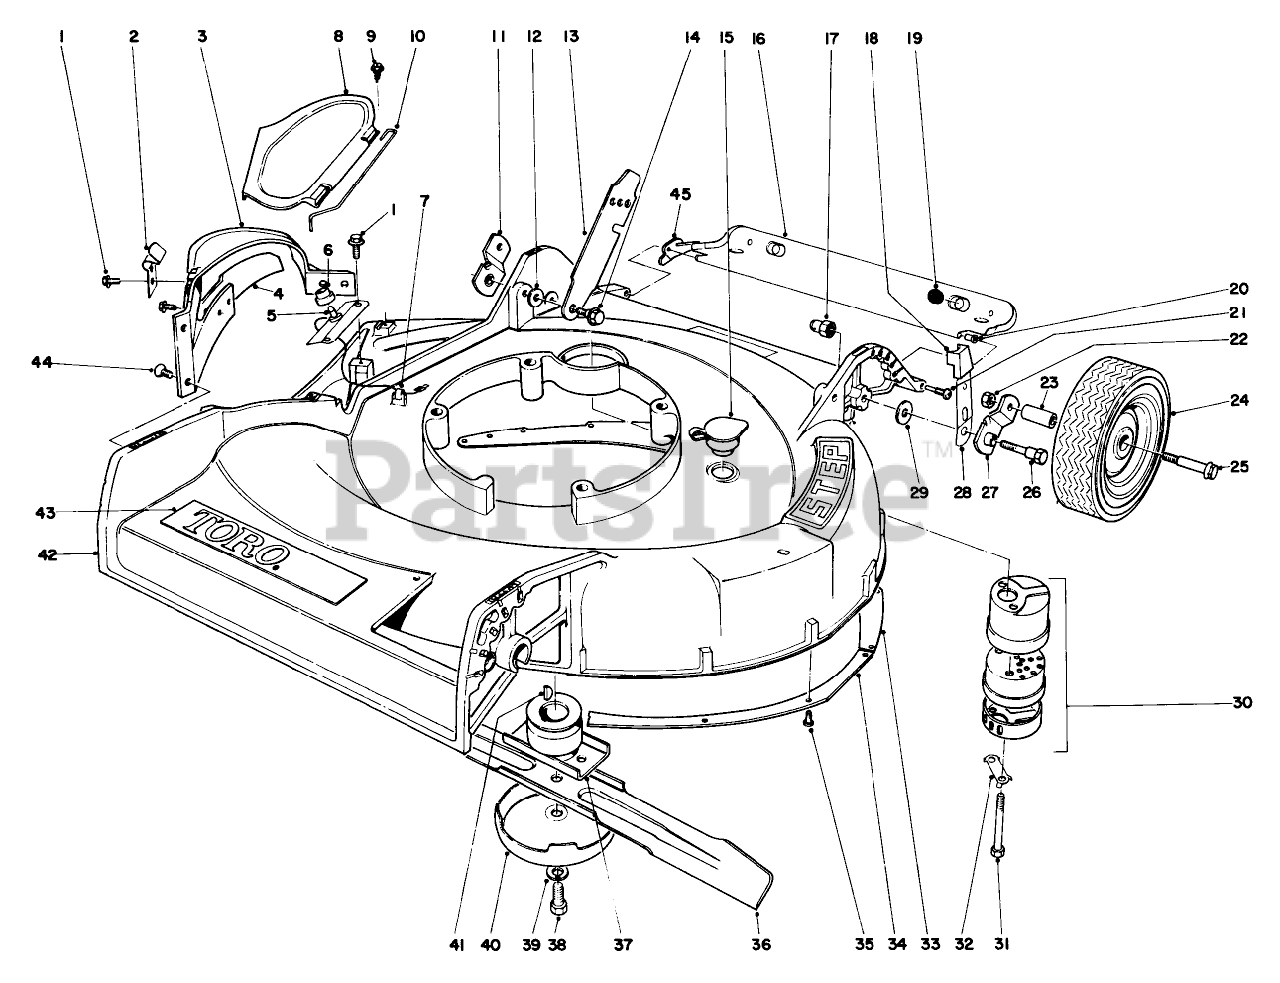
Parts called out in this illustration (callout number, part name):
3	Deflector (Incl. Ref. Nos. 1-4)
4	DefIector Bar
8	Deflector Cover
9	SCREW
10	Hinge Spring
12	SPACER
14	SCREW-SHOULDER
15	WASHOUT PLUG
17	HANDLE PIVOT NUT
26	5/16-18 PIVOT SCREW
29	WASHER-PIVOT
30	MUFFLER ASM
31	SCREW-HH
32	CLIP - LOCKING
34	Secondary Skirt
37	BLADE RETAINER WA
39	WASHER-LOCK
41	KEY-WOODRUFF
42	Housing (Incl. Ref. #33, 34 35)
43	Toro Emblem
